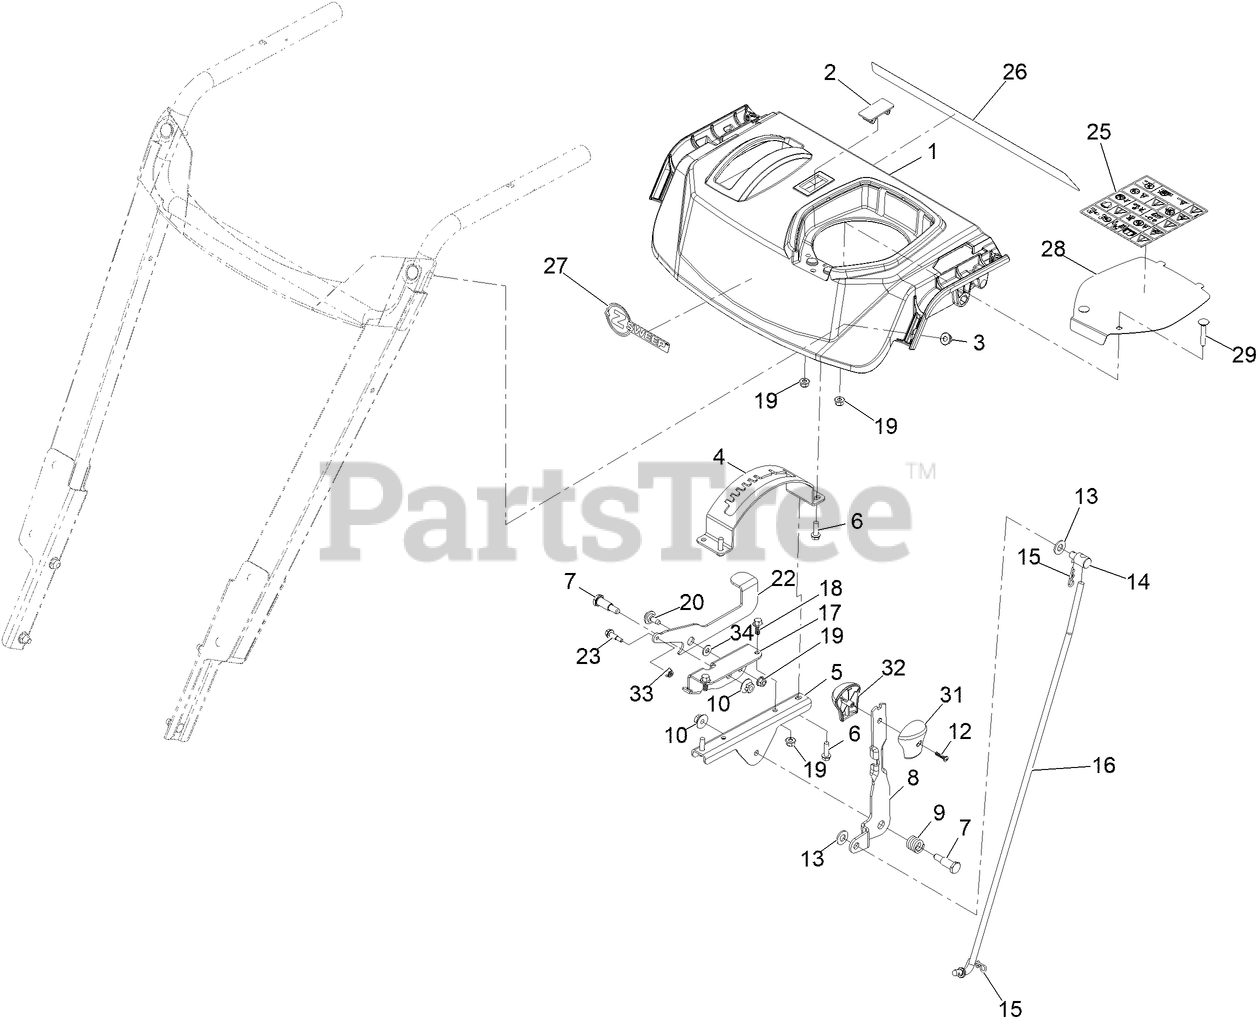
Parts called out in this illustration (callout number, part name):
1	PANEL-CONTROL
2	PLUG-HOLE
4	GATE-SHIFT
5	BRACKET-SHIFT
6	SCREW-PLASTITE, HWH
7	SCREW-SHOULDER, HH
8	SELECTOR-SPEED
9	SPRING-COMPRESSION
12	SCREW-PPH
13	WASHER-FLAT
14	TRUNNION-ROD
15	PIN-HAIR
16	ROD-SHIFT
17	BRACKET-LEVER, BROOM ANGLE
18	Screw-HHF 1/4-20 X 5/8
19	SCREW-SHOULDER
20	SCREW-SHOULDER
22	LEVER-BROOM ANGLE
23	SCREW-SHOULDER
25	PLATE-COVER, CONT PNL
26	BOLT-CARR
27	KNOB-SHIFT, LH
28	PLATE-COVER, CONT PNL
29	BOLT-CARR
31	KNOB-SHIFT, LH
32	KNOB-SHIFT, RH
34	Washer-Flat
